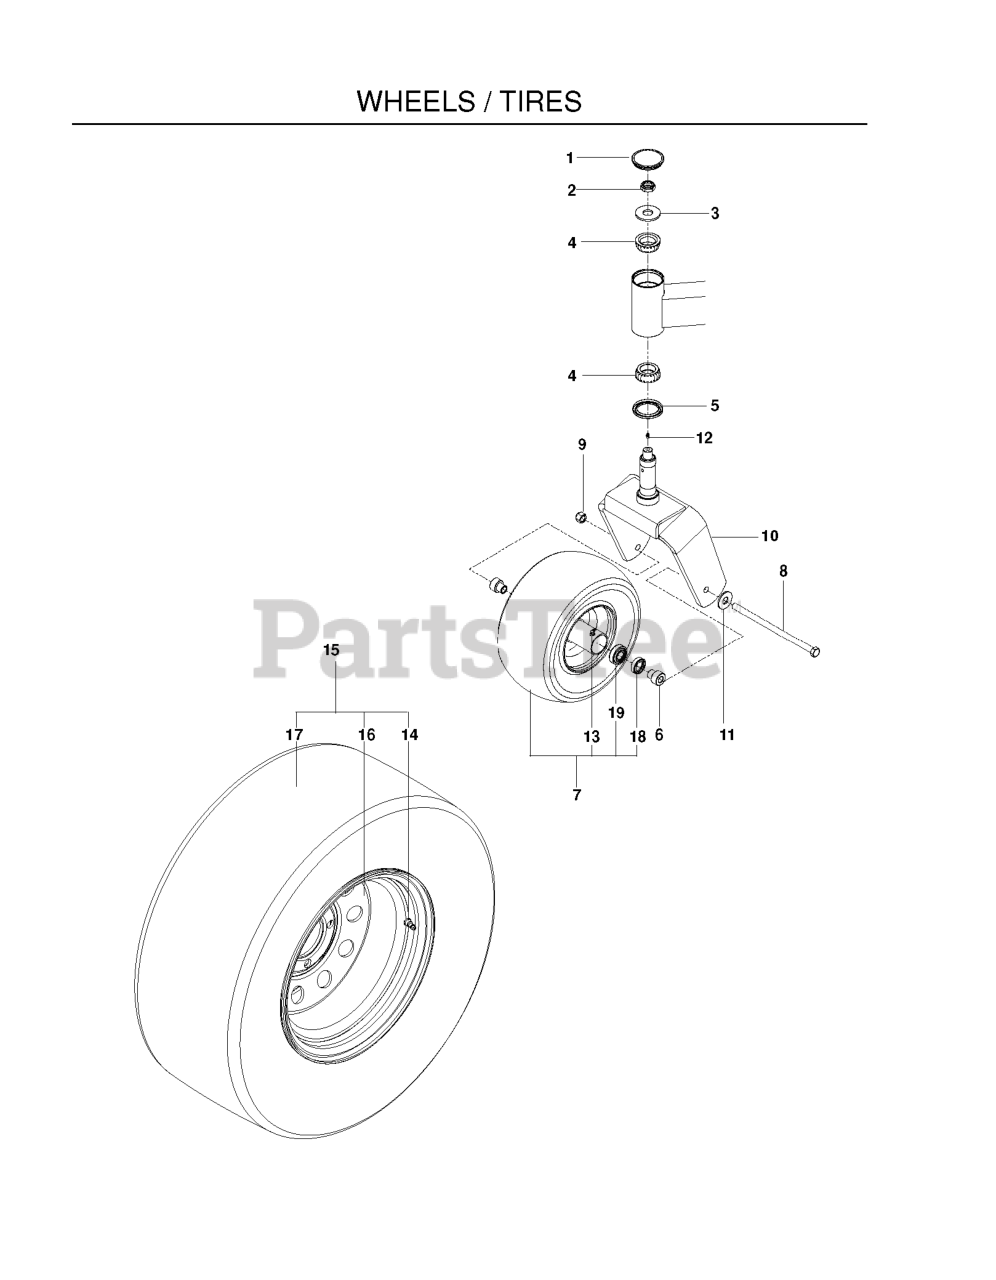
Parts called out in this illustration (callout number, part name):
2	NUT, 3/4-16 HEX THIN NYLOC ZD
3	WASHER, 3/4 HARDENED
4	BEARING W/CUP TAPPER ROLLER
5	SEAL, BEARING
6	AXLE SPACER
7	TIRE, 13 X 6.5-6 NO FLAT
8	HEX SCREW 1/2-13 X 9.5 GR5
9	NUT, 1/2-13 HEX FLG NYLOC ZD
10	FORK.CASTER.ORANGE
11	WASHER 1/2" FLAT
12	ZERK
13	ZERK
14	VALVE STEM TR-412
15	WHEEL/TIRE.ASM.24X12-12.SILVER
16	RIM, 12 X 8.5 W/1.75 NEG OS
17	WHEEL/TIRE.ASM.24X12-12.SILVER
19	TAPERED BEARING W/RACE
